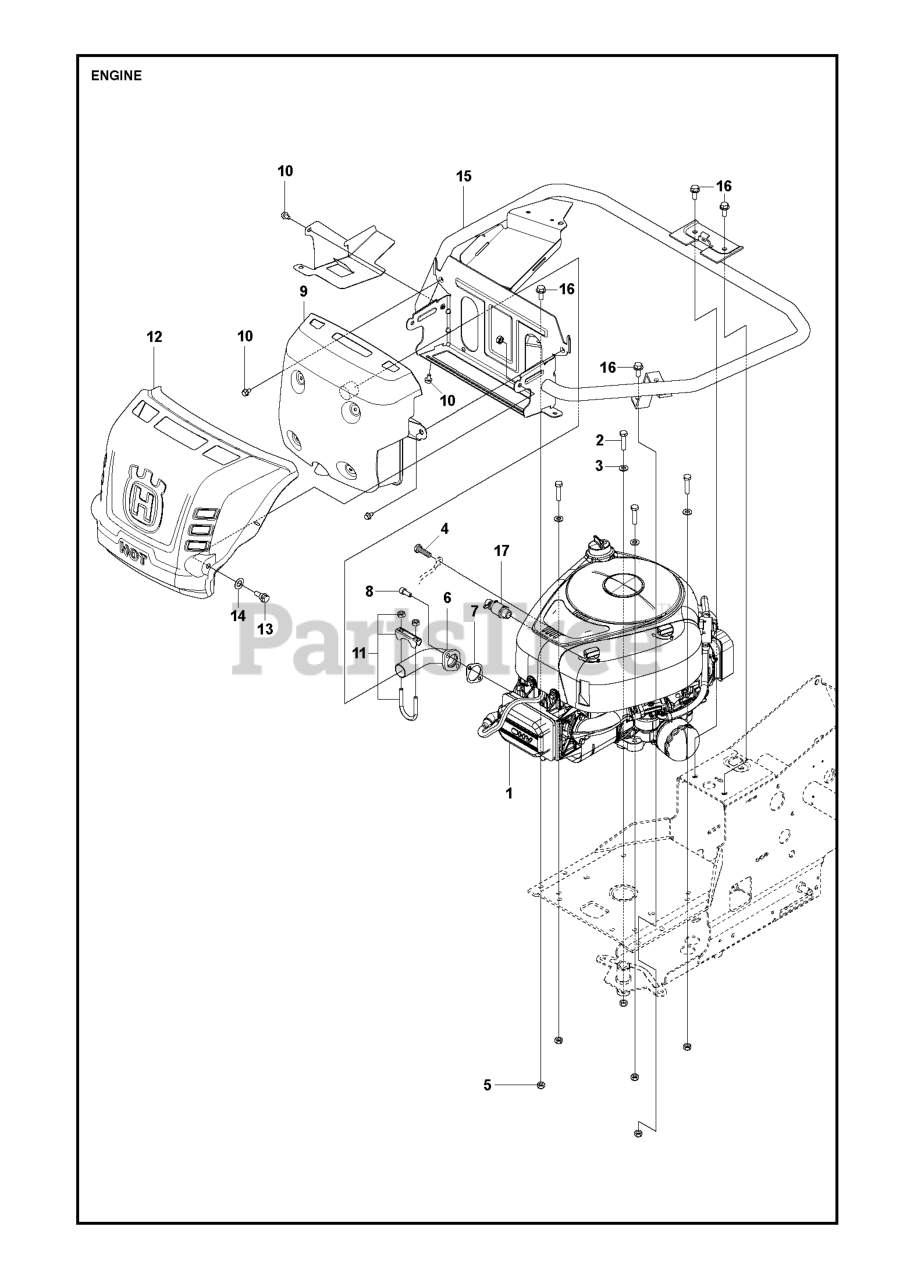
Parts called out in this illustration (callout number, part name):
3	WASHER BRB 8.4X17
5	LOCKNUT M8
11	CLAMP ASSY EXHAUST
12	HEAT SHIELD
14	SPRINGWASHER
17	VALUE.OIL.DRAIN
